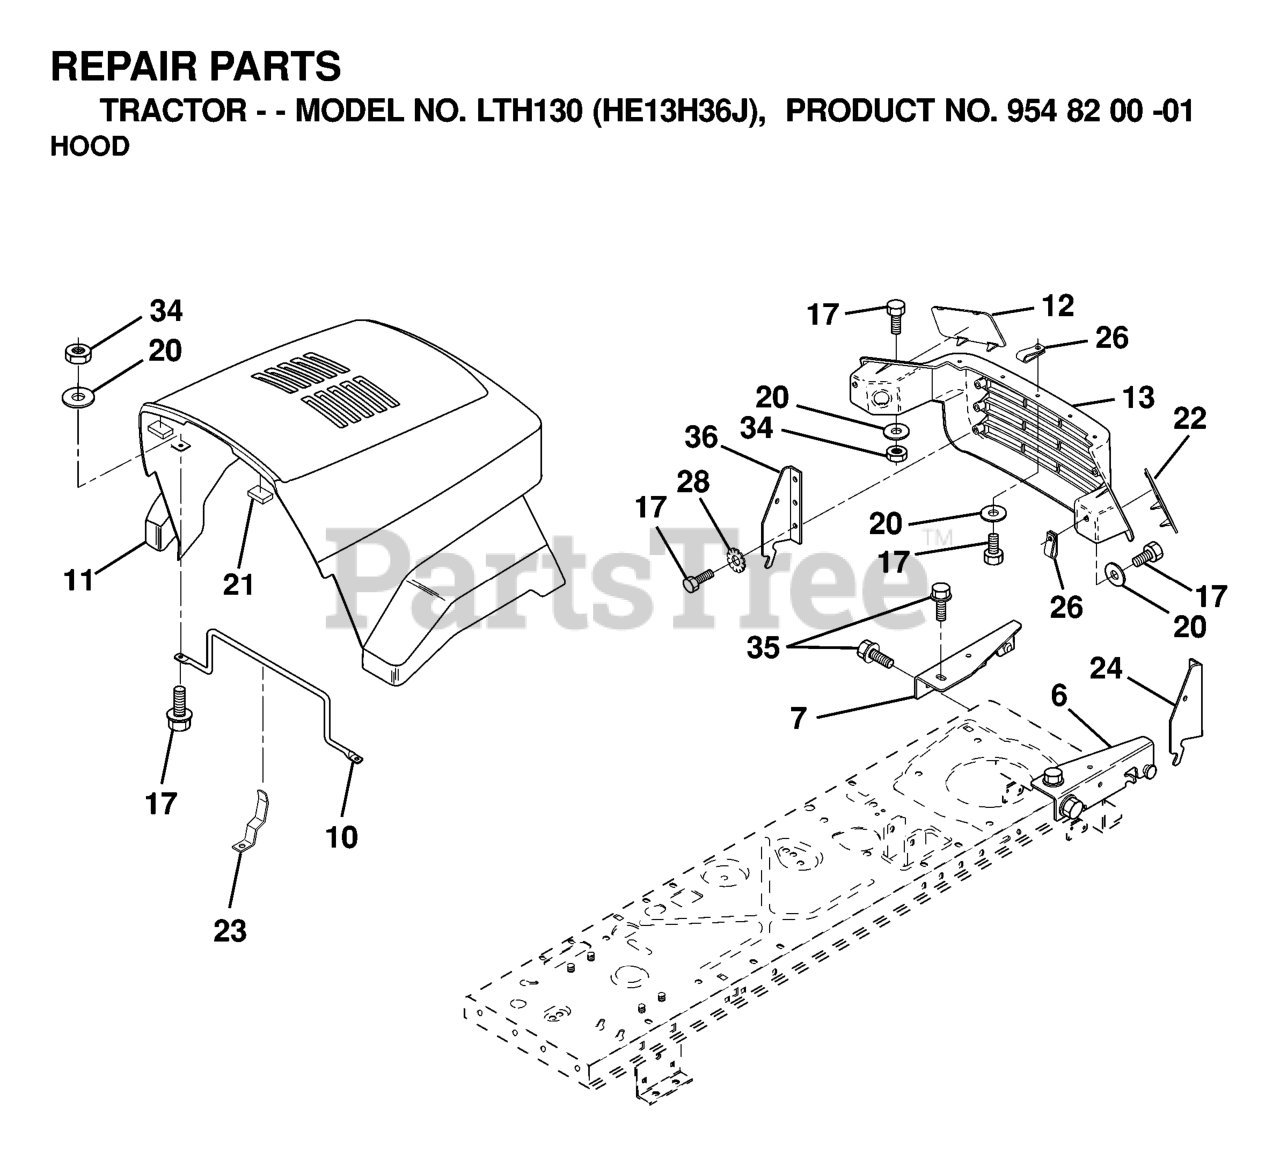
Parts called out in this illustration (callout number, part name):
6	BRACKET ASSY HOOD
7	BRACKET ASSY
10	BRACE HOOD
11	HOOD
12	LENS/LH
13	GRILLE
17	BOLT
21	BUMPER HOOD T
22	LENS
23	HOOD LATCH
24	BRACKET PIVOT
26	CLIP TINNERMAN
28	Washer, Lock, External Tooth 1/4
34	NUT.CROWNLOCK.1/4
35	SCREW.THDROL.5/16-18X3/4.TTY
36	BRACKET HOOD
